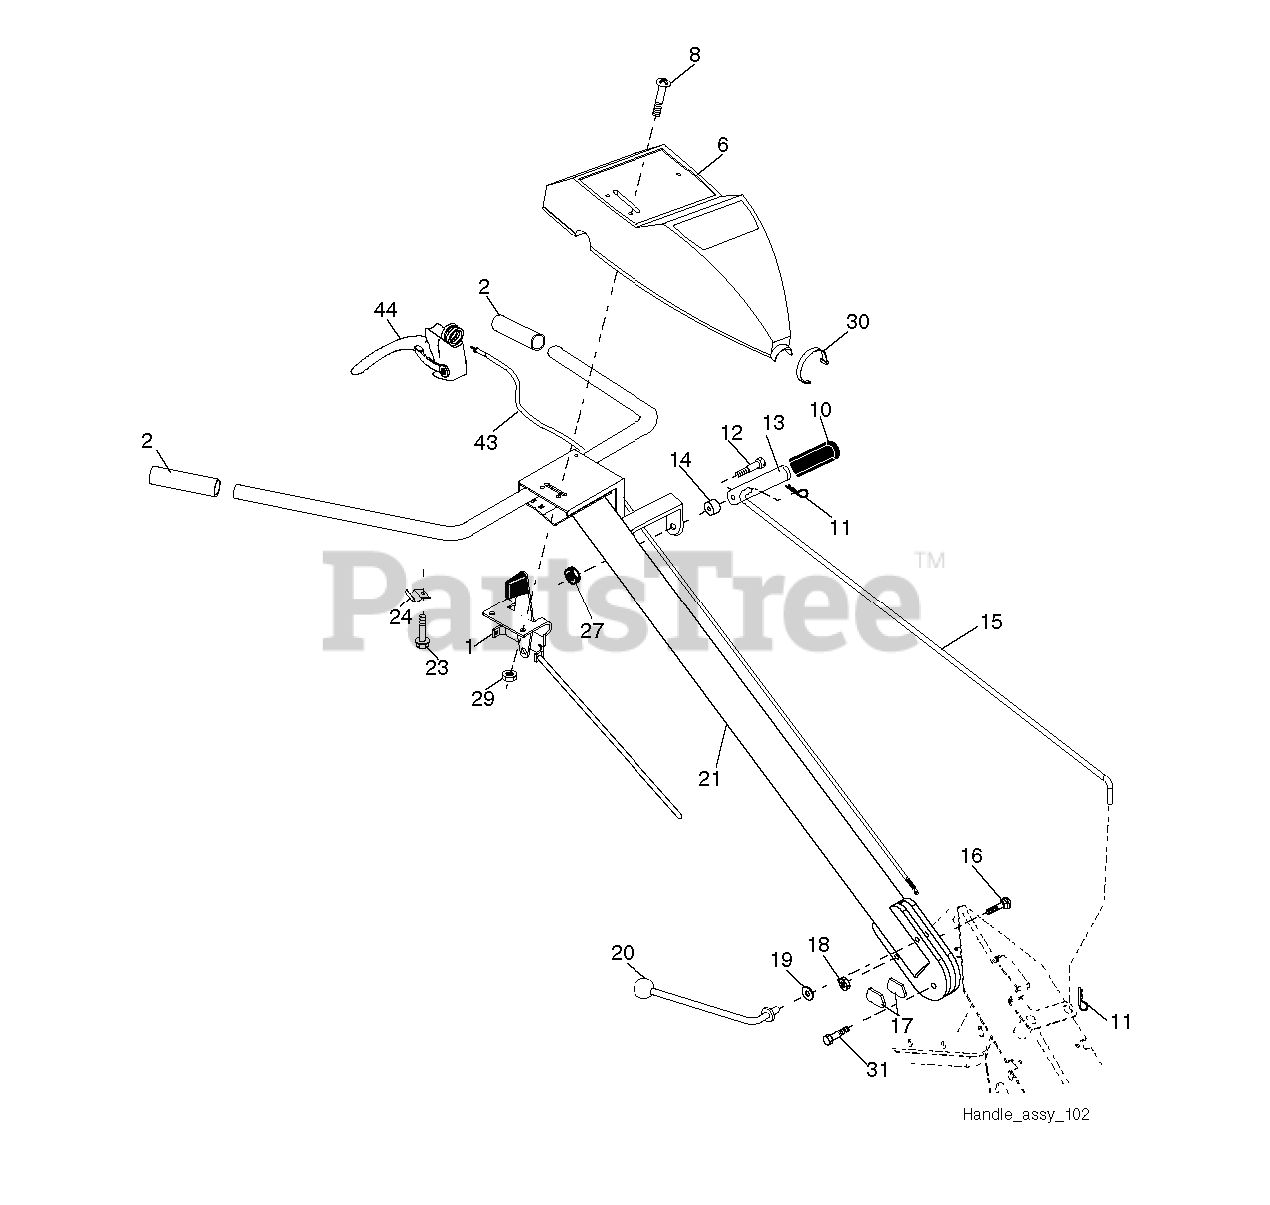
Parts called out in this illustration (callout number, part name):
1	CONTROL.THROTTLE
2	GRIP.1X5.06
6	RP CONTROL PANEL
8	SCREW.PNHD.10-24
10	GRIP T
11	RETAINER M
12	SHOULDER BOLT ST
13	HANDLE.SHIFT.TILLER
14	GROMMET.RUBBER.CRT.TILLER
15	SHIFT ROD CRT
16	BOLT D
17	LOCK.HANDLE.CRT
19	WASHER CRT
20	LEVER.LOCK.CRT
21	REPL BY 532 1805-17
23	TAPPING SCREW
24	CONDUIT.CLIP.PLATED
27	NUT T
29	NUT **
30	TIE CABLE CRT
31	BOLT.PIVOT
43	CABLE.HANDLE.TINE.CONTROL.CE
44	CONTROL.HANDLE.TWO.FUNCTION.CE
